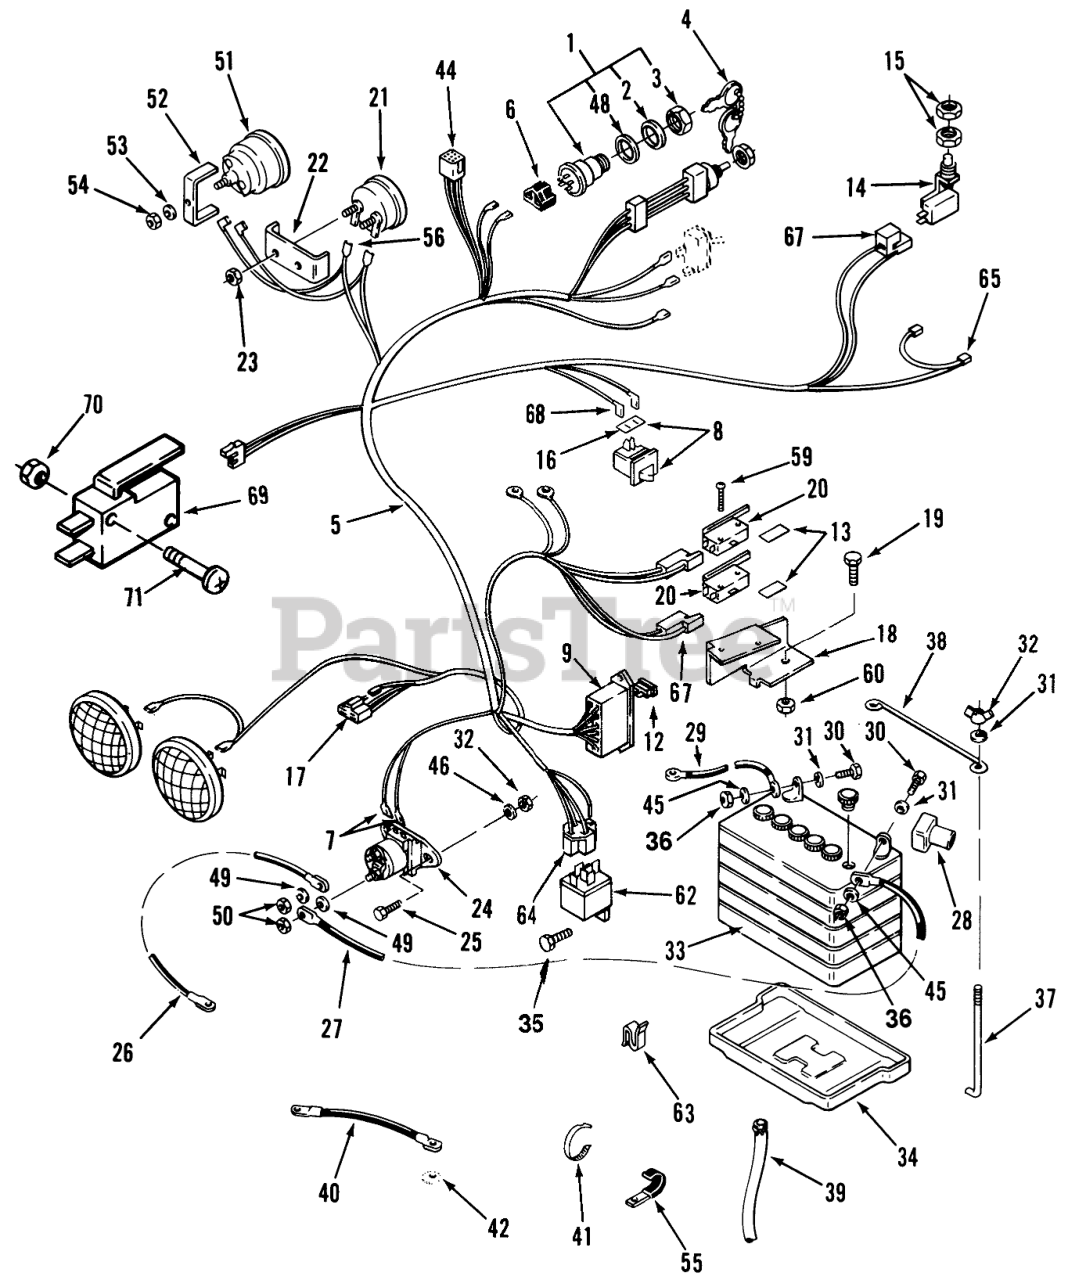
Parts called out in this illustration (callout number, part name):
1	Ignition Switch Ass-y
2	LOCKWASHER
4	Ignition Key
5	MAIN-HARNESS & DIA
6	CONNECTOR BODY ELECT
7	TERMINAL 10
8	SWITCH INTERLOCK
9	FUSE-HOLDER 4 WAY
12	FUSE-BLADE, 15 AMP
13	BARRIER - SWITCH
14	Seat Switch
15	NUT-HEX, SPECIAL
16	SHIELD-DIRT SPST
17	5-CONTACT CONN BODY
18	BRACKET-SWITCH
19	Bolt
20	SWITCH
21	VOLTMETER
22	CLAMP-MOUNTING
23	HEX NUT 10-32 E.S.
24	Solenoid
25	Screw
26	ASSY WIRE
27	CABLE-BLACK
28	Boot
29	ASSY WIRE
30	Bolt
32	Nut
33	Battery
34	TRAY-BATTERY
37	HOOK-BATTERY RETAIN
38	HOLDDOWN-BATTERY
39	TUBE-21" BATTERY DRAIN
40	WIRE GROUND
41	PLASTIC TIE
42	Washer-Lock
44	Terminal
45	Washer
48	Washer
49	Washer
50	Nut
51	Hour Meter Complete (Includes Items 52-54) 312-8, 312-H, 416-8 & 416-H
52	BRKT-GAUGE MOUNTING
53	Lockwasher
54	Hex Nut
55	CLIP
59	Screw
60	NUT HEX 4-40 ELAST
62	RELAY
63	CLIP-CABLE
64	TERMINAL 10
65	Sur-Plug
67	CONNECTOR BODY
68	Terminal
69	SWITCH
70	NUT HEX 4-40 ELAST
71	Screw
